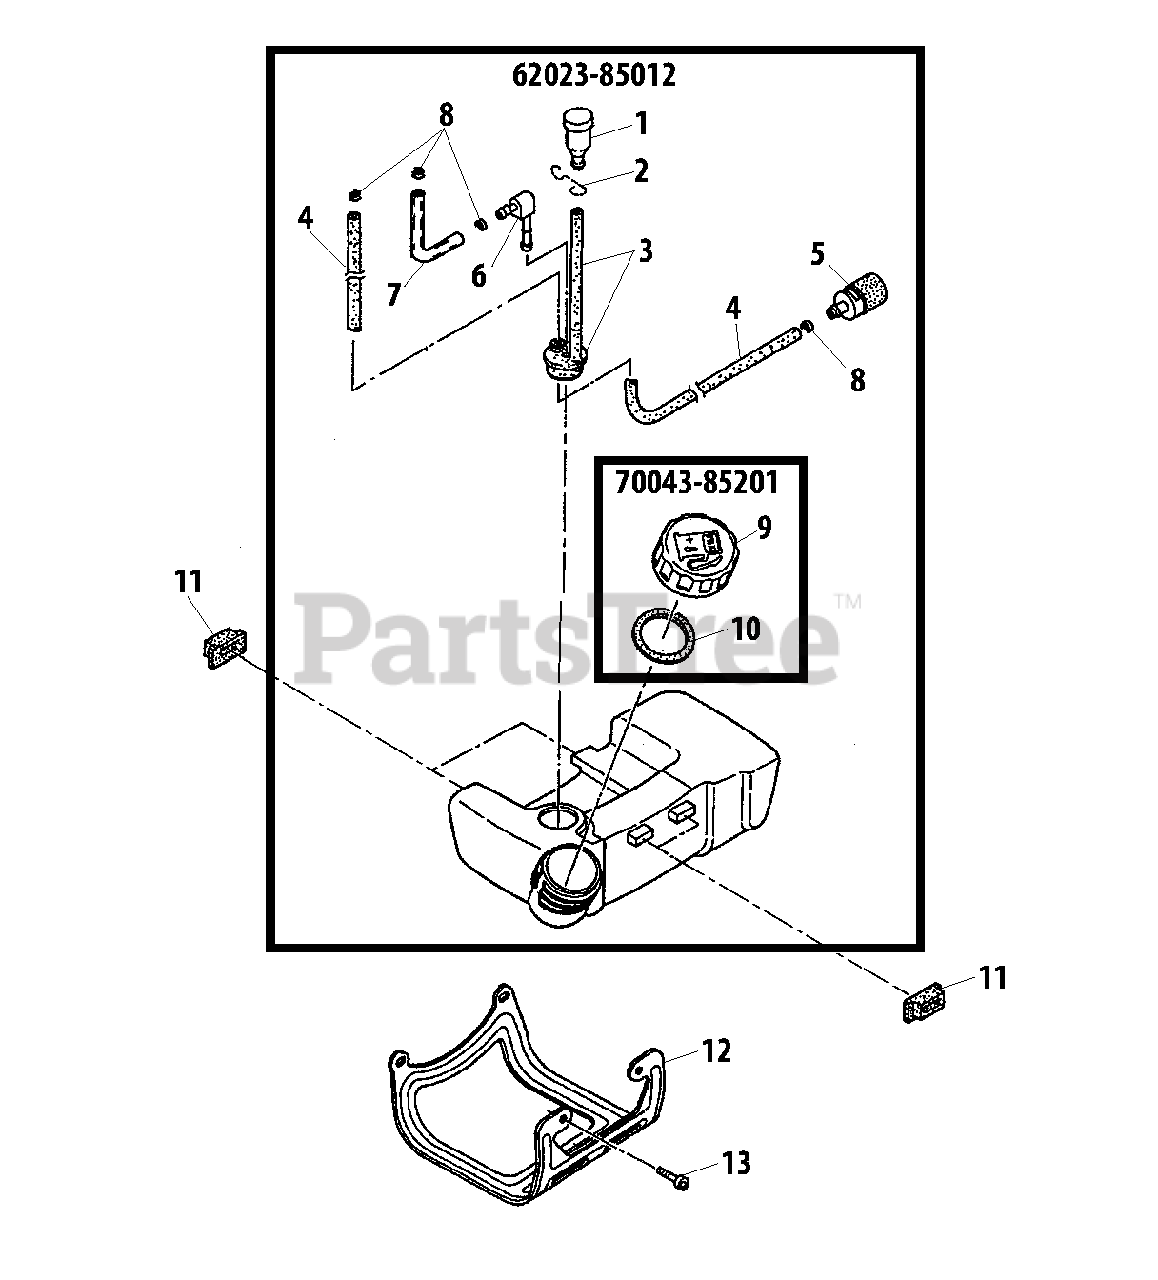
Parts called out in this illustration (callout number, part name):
1	VENT, FUEL TANK
2	HOLDER, VENT
3	VENT PIPE ASSY
4	PIPE - FUEL
5	FILTER, FUEL
6	CONNECTOR, PIPE
7	PIPE - RETURN
8	RING, RETAINING - 6
9	CAP, FUEL
10	GASKET, CAP
11	CUSHION, TANK
12	GUARD, FUEL TANK
13	SCREW - 5X12
62023-85012	FUEL TANK ASSY
70043-85201	CAP ASSY
